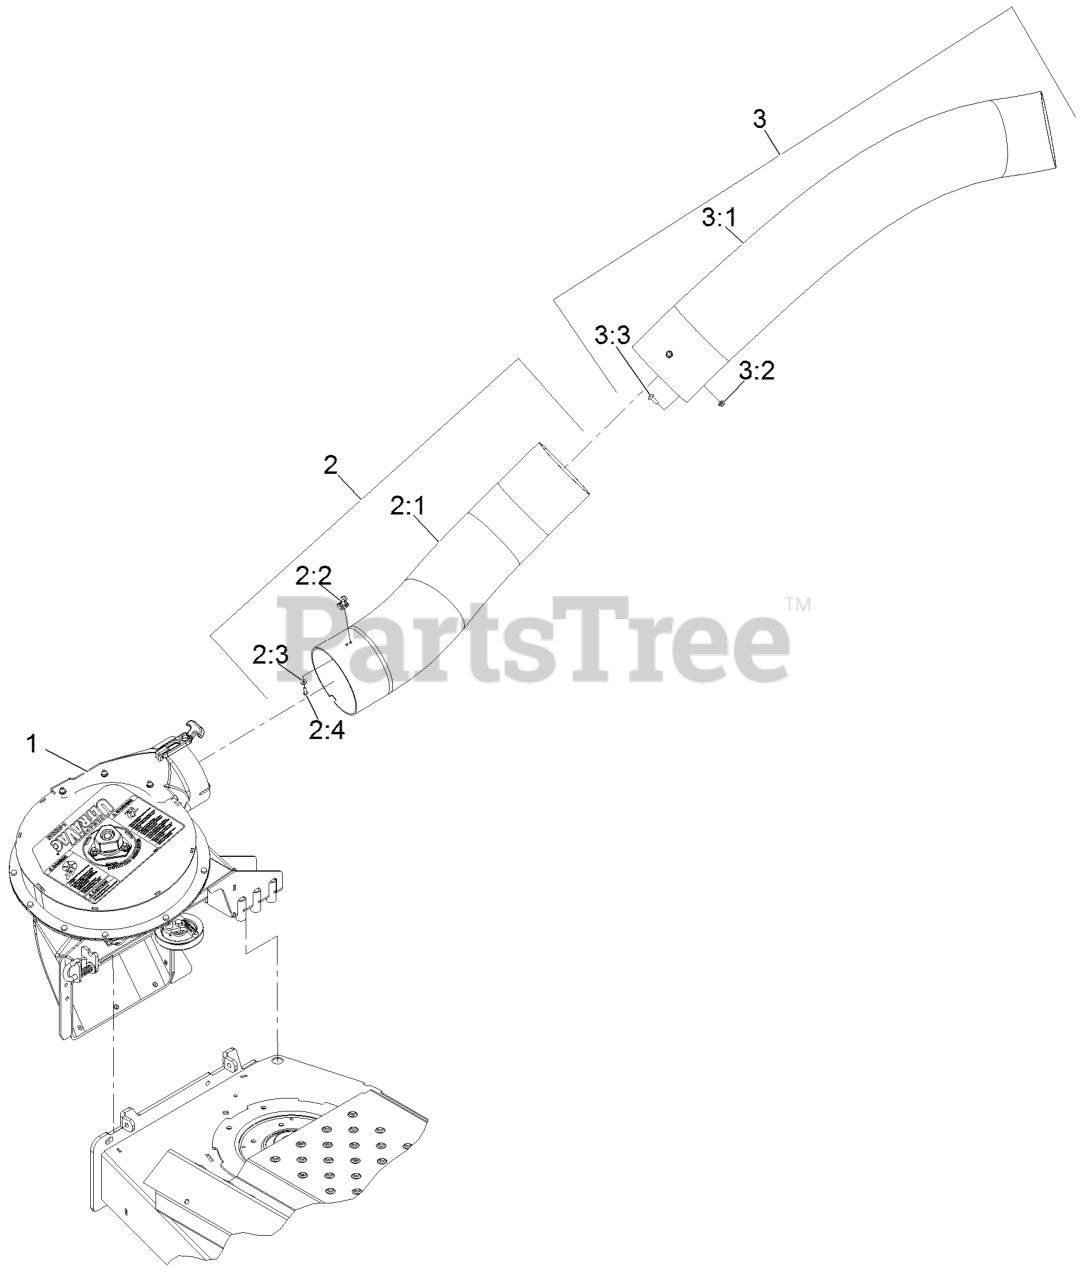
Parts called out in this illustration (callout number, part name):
1	ASM-BLOWER UV E SERVICE
2	LOWER TUBE ASM
2:1	TUBE-LOWER
2:2	LATCH-KEEPER
2:3	WASHER-FLAT
2:4	SCREW-PPH
3	UPPER TUBE ASM
3:1	TUBE-UPPER
